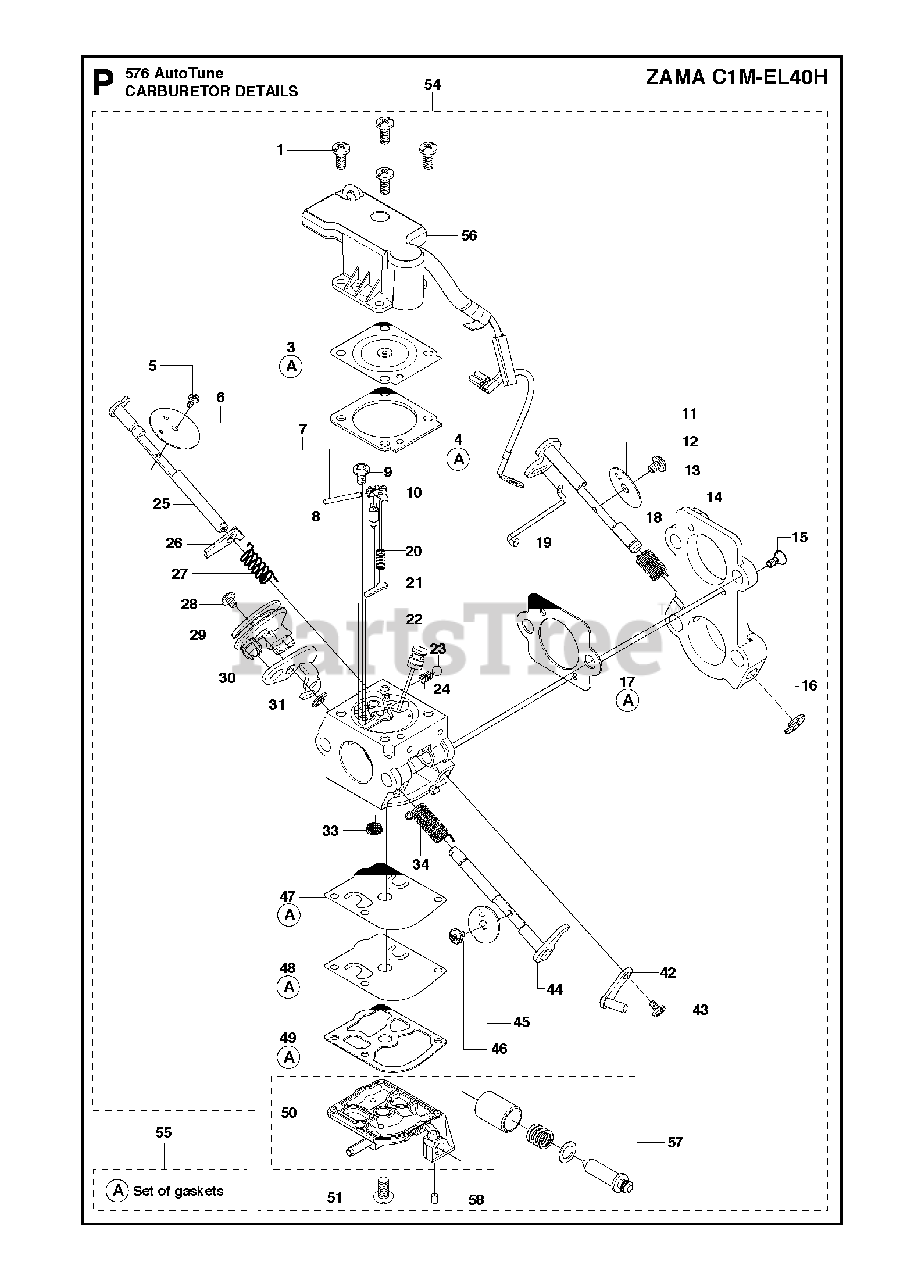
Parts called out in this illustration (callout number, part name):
1	Screw
3	DIAPHRAGM
4	GASKET METERING
5	SCREW
6	CHOKE VALVE
7	PIN FULCRUM
8	INLET NEEDLE
9	SCREW
10	LEVER
11	SHAFT
12	THROTTLE FLAP
13	SCREW
14	RP CARBURETOR
15	SCREW
16	CLIP
17	GASKET
18	SPRING
19	ROD
20	SPRING
21	PLUG
22	JET
23	BALL
24	SPRING
25	CHOKE SHAFT
26	LEVER
27	SPRING
28	SCREW
29	THROTTLE LEVER ASSY
30	LEVER
31	CLIP
33	STRAINER
34	SPRING
42	LEVER
43	SCREW
44	THROTTLE SHAFT
45	FLAP
46	SCREW
47	PUMP DIAPHRAGM
48	DIAPHRAGM
49	GASKET
51	SCREW
54	CARBURETTOR C1M-EL40H
55	GASKET SET KIT
56	VALVE HOUSING ASSY
57	IDLE SPEED SCREW TAMPERPROOF K
58	PLUG
